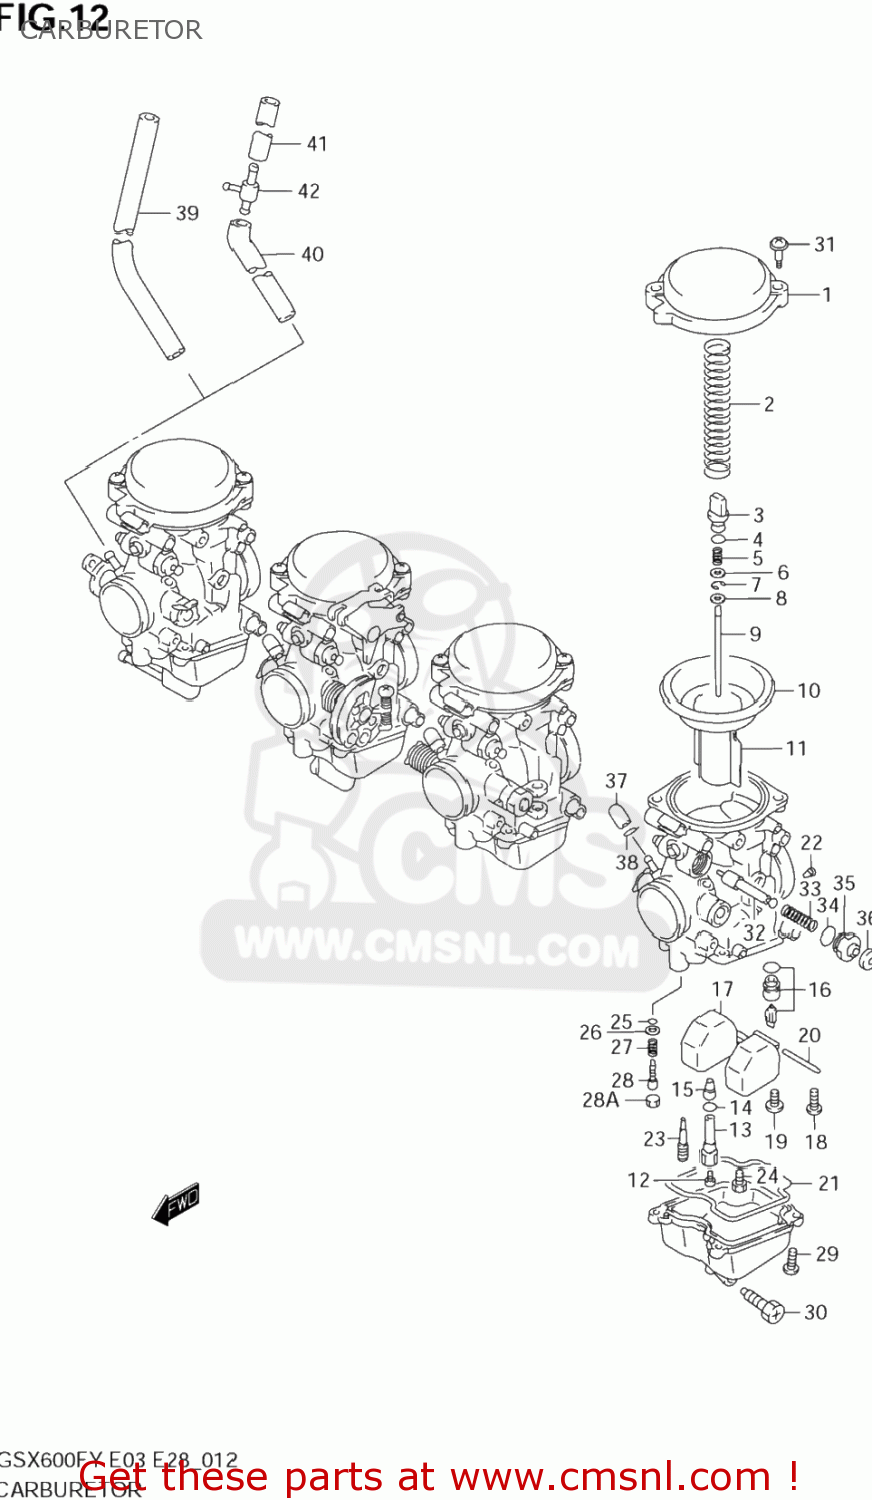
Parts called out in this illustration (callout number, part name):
1	COVER,DIAPHRAGM
2	SPRING
3	HOLDER
4	O RING(D:1.9,ID:4.8)
5	SPRING
6	WASHER
7	E RING,MULTIPLE JET NOZZLE
8	RING
9	NEEDLE,JET
10	DIAPHRAGM
11	VALVE,PISTON
12	JET,MAIN(115)
13	HOLDER,JET
14	O RING
15	JET,NEEDLE(P-0M)
16	VALVE ASSEMBLY,NEEDLE
17	FLOAT ASSY
18	SCREW
19	SCREW
20	PIN,FLOAT
21	GASKET (NAS)
22	JET,AIR(160)
23	JET,PILOT(12.5)
24	JET,STARTER(50)
25	O RING,PILOT AIR SCREW
26	WASHER
27	SPRING,THROTTLE SCREW
28	ADJUSTER
28A	PLUG
29	SCREW
30	SCREW,DRAIN
31	SCREW
32	PLUNGER
33	SPRING
34	O RING
35	GUIDE SCREW,PLUNGER
36	CAP,STARTER VALVE
37	CAP
38	CLIP
39	HOSE
40	HOSE
41	HOSE
42	NIPPLE
